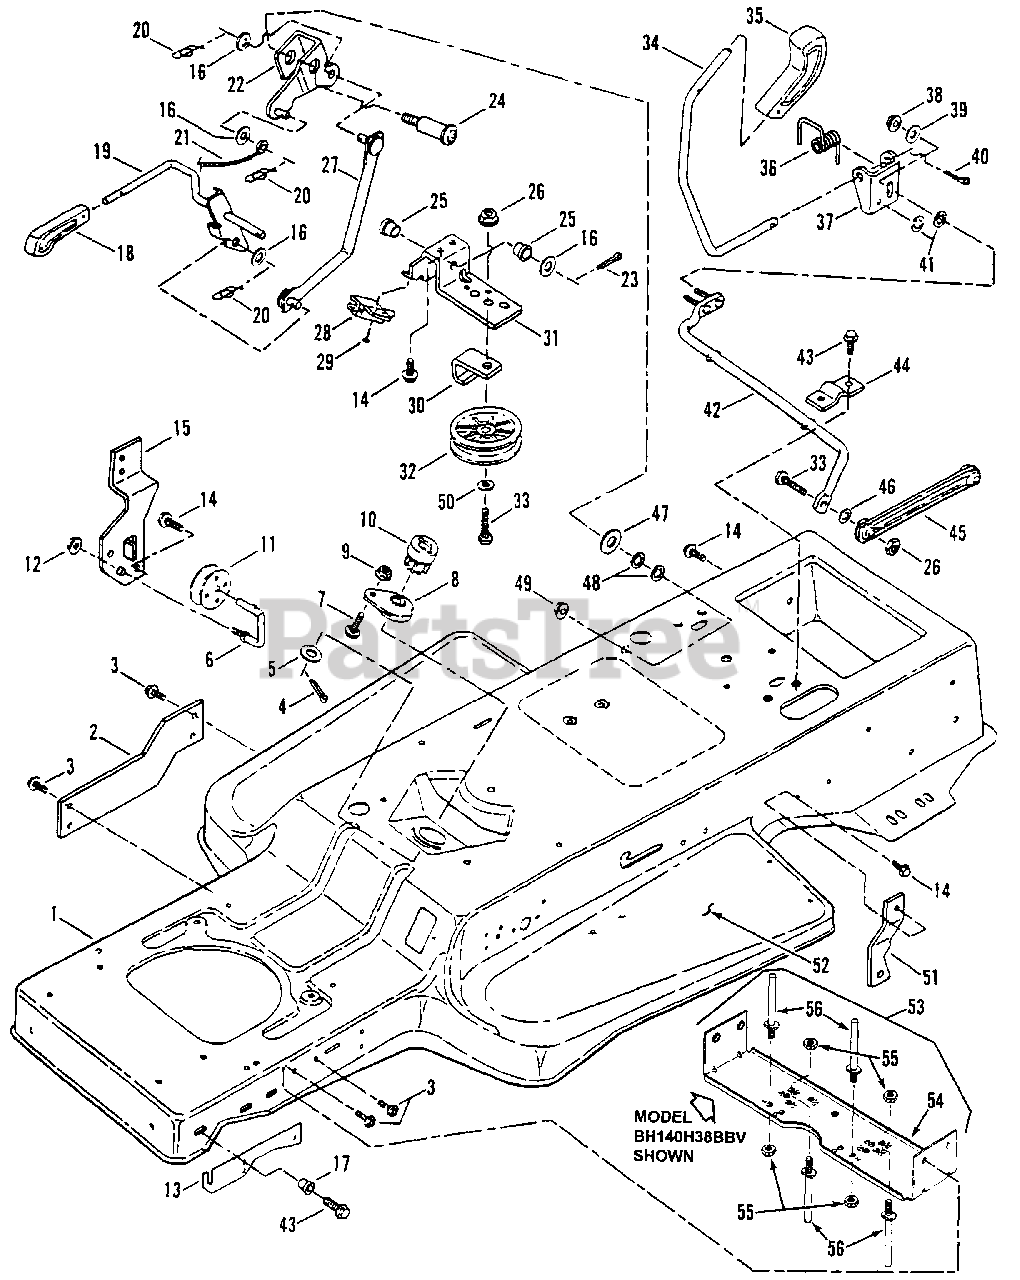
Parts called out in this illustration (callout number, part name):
1	FRAME, Tractor
2	BRACE, Frame
3	SCREW, 5/16-18 x 5/8" Truss Head (Torx)
4	COTTER-PIN, 1/8 x 3/4"
5	WASHER, 1/2 Shim
6	ROD, Spool Pivot
7	BOLT, 1/4-20 x 5/8" Short Neck Carriage
8	ASSEMBLY, Steering Adjuster
9	NUT, 1/4-20 Hex Flange Lock
10	GEAR, Steering Pinion
11	SPOOL
12	NUT, 5/16-18 Hex Flange Lock
13	BRACKET, Hood Pivot
14	SCREW, 5/16-18 x 5/8" Self-Tapping
15	BRACKET, Axle/Spool
16	WASHER, 3/8" Flat
17	BUSHING, Flange
18	KNOB, Deck Engagement
19	WELDMENT, PTO Lever
20	PIN, 3/64 x 1 7/32" Self-Lock'g.
21	CABLE, Blade, 20.13"
21	CABLE, Blade, 21.56"
22	WELDMENT, PTO Bellcrank
23	COTTER-PIN, 3/32 x 3/4"
24	BOLT, 1/2-13 x 2 11/32" Shoulder
25	BUSHING
26	NUT, 3/8-16 Hex Center Lock
27	ROD, PTO Link
28	SWITCH
29	SCREW, #10-24 x 1/2" Hex Washer Self-Tap (Torx)
30	GUIDE, Belt
31	SUPPORT, PTO Lever
32	PULLEY
33	SCREW, 3/8-16 x 1 1/2" Hex Hd. Cap
34	LEVER, Shift
35	KNOB, Deck Lift Lever
36	SPRING, Shift Lever
37	BRACKET, Shift Lever (Upper)
38	NUT, 1/4-20 Hex Flange Lock
39	WASHER, 1/4 Flat
40	COTTER-PIN, 5/32 x 1"
41	WASHER, 1/4 Internal Tooth Lock
42	ASSEMBLY, Shift Lever (Lower)
43	SCREW, 5/16-18 x 1 1/4" Self-Tap.
45	LINK, Shift Lever
46	SPACER
47	WASHER, Thrust
48	WASHER, 1/2 Internal Tooth Lock
49	NUT, 1/2-13 Hex Flange Lock
50	WASHER, 3/8" Flat
51	BRACKET, Torque
52	PAD, Foot, Sandpaper
52	PAD, Foot, Rubber Deluxe
53	GUIDE ASSEMBLY, Belt (NLA)
54	BRACKET, Belt Guide
55	NUT, 5/16-18 Hex Lock
56	STUD, Belt Guide
